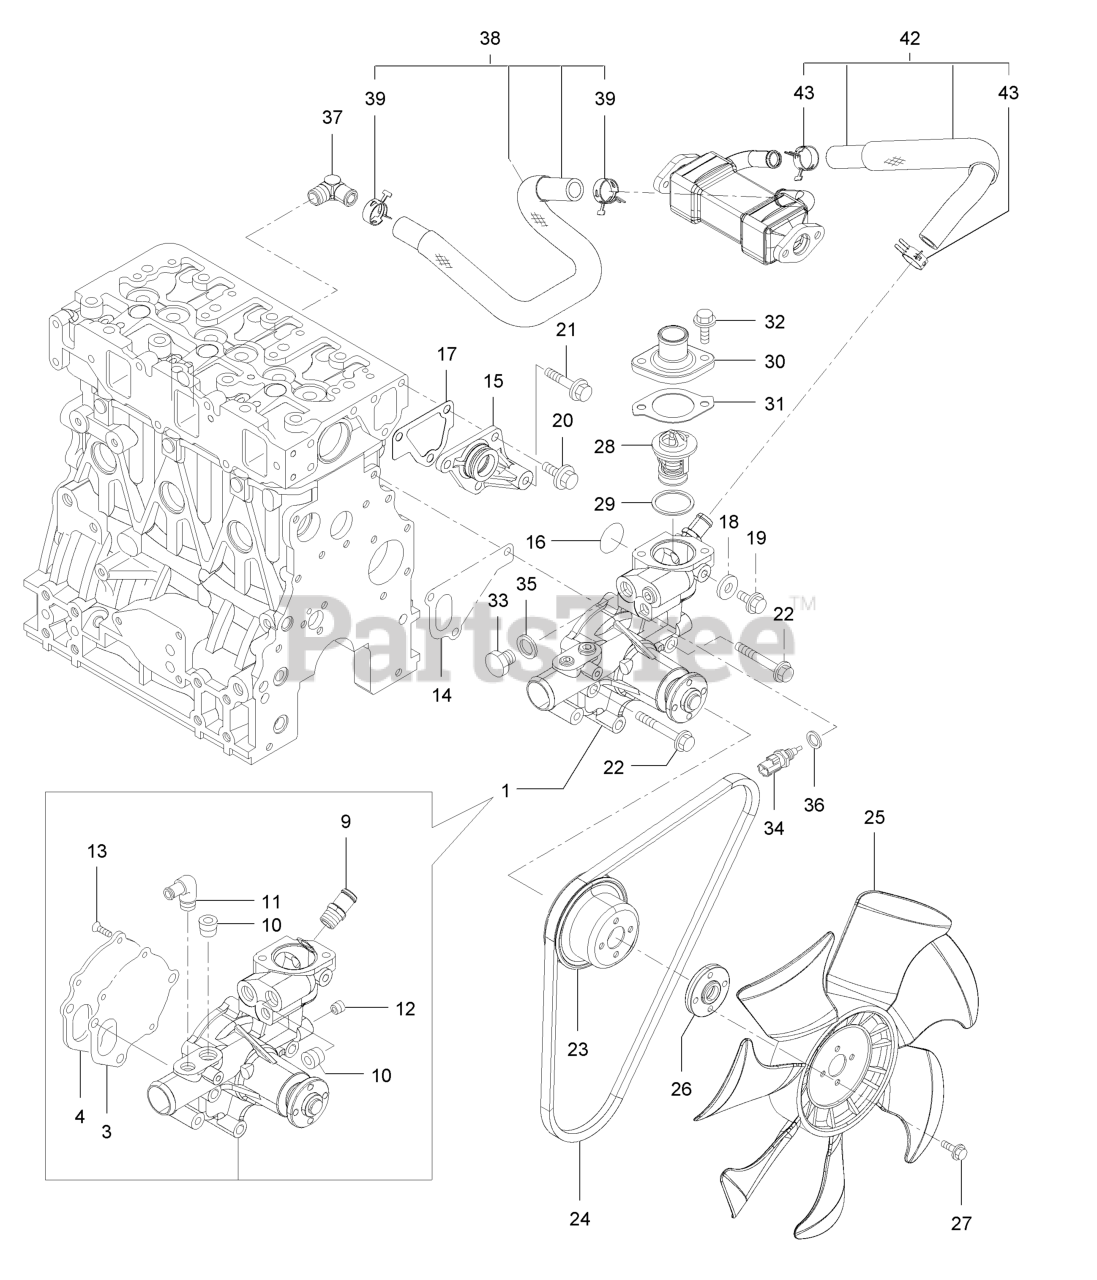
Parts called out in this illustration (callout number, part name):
1	Water Pump ASM
20	Bolt
23	V-Pulley
28	Thermostat
34	Sensor-Thermostat, CW
36	Washer-Seal
38	E G R-C Pipe ASM
39	Clip-Hose
42	CW Pipe ASM
43	Clip-Hose
